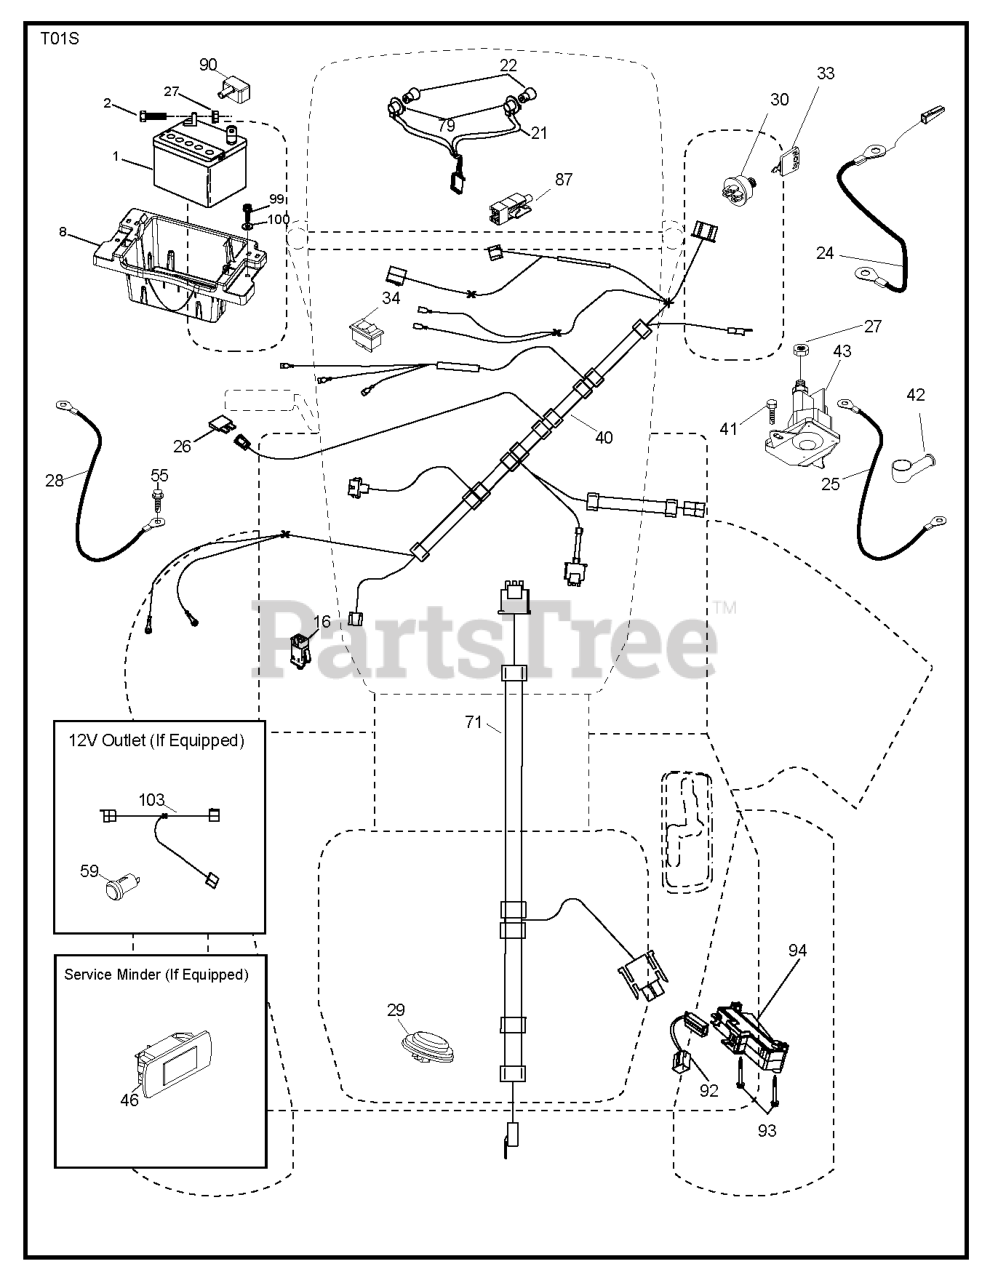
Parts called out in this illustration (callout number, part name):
1	Battery 12 Volt 25 Amp
2	BOLT.HEX.1/4.X.3/4.DICHROMATE
8	TRAY.ASM.BATTERY.FRT.TEX.CARB
16	SWITCH INTERLOOK PUSH-IN
21	HARNESS.LIGHT W/4152J BULBS
24	CABLE.FRBATT.W/WIRE.8GA.8
25	CABLE.STARTER.8GA.17.5
26	FUSE 20AMP
28	CABLE.GROUND.21"BLK.8GA.90T
29	SWITCH.SEAT.DELTA.OPC.
30	SWITCH.IGN.DELTA.W.LGH.ROS
33	KEY.CHAIN.BLISTER.PACK.GEN.USA
40	HARNESS.IGN.DASH.CBL.YTGT.PRED
41	SCREW
42	TERMINAL COVER
55	SCREW 5/16"
71	HARNESS-CHASSIS SUB
79	BULB HOLDER ASM.
87	SWITCH.INTRLCK.CLUTCH.
90	COVER.TERMINAL.BATTERY
92	HARNESS.PIGTAIL.CONSLE
94	MODULE.REVERSE.ROS
99	SCREW HEXWSHR 1/4-20X3/4
